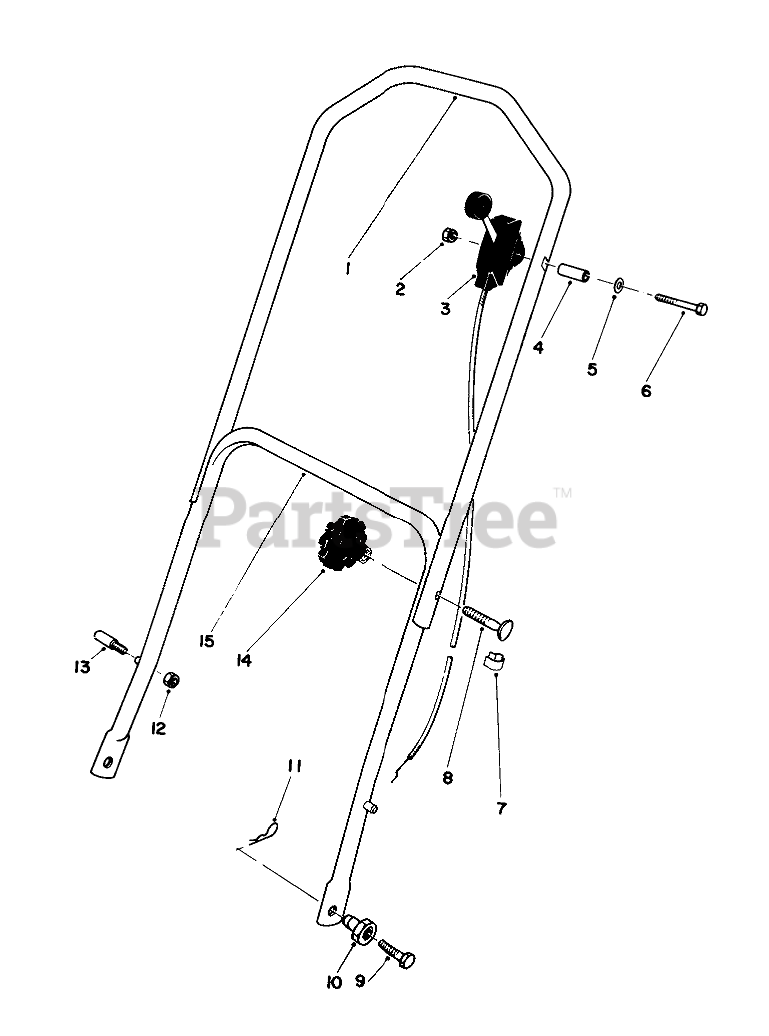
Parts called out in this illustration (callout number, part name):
1	Handle-Upper
2	Locknut
3	SERVICE THROTTLE CONTRO
4	Spacer
5	WASHER
6	SCREW-HH
8	5/16-18 X 2 HNDLE SCREW
9	SCREW-HH
10	HANDLE PIVOT NUT
11	PIN-COTTER, HAIR
12	NUT-LOCK, NI
13	HANDLE PIN
15	LOWER HANDLE ASM
